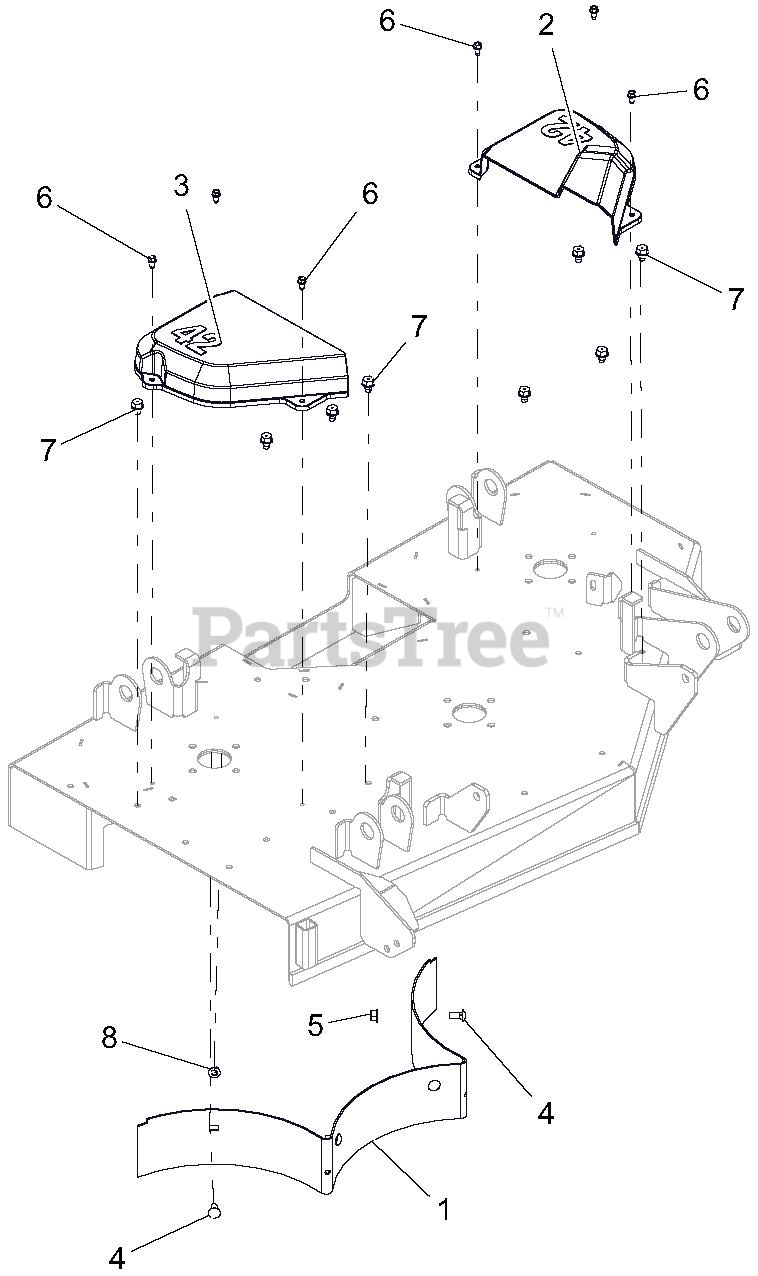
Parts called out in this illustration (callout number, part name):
1	BAFFLE, REAR 42"-RED
2	COVER, BELT 42" LEFT
3	COVER, BELT 42" RIGHT
4	BLT-RDHDSQNK .31-18X.75 G5 YWZC
5	NUT, LK-TOP-FLG .38-16 YWZC
6	SCR-TAP .25-20X.50 HWH TR YWZ
7	SCR-TAP .38-16X.50 HWH TR YWZ
8	NUT, LK-TOP-FLG .312-18 YWZC
